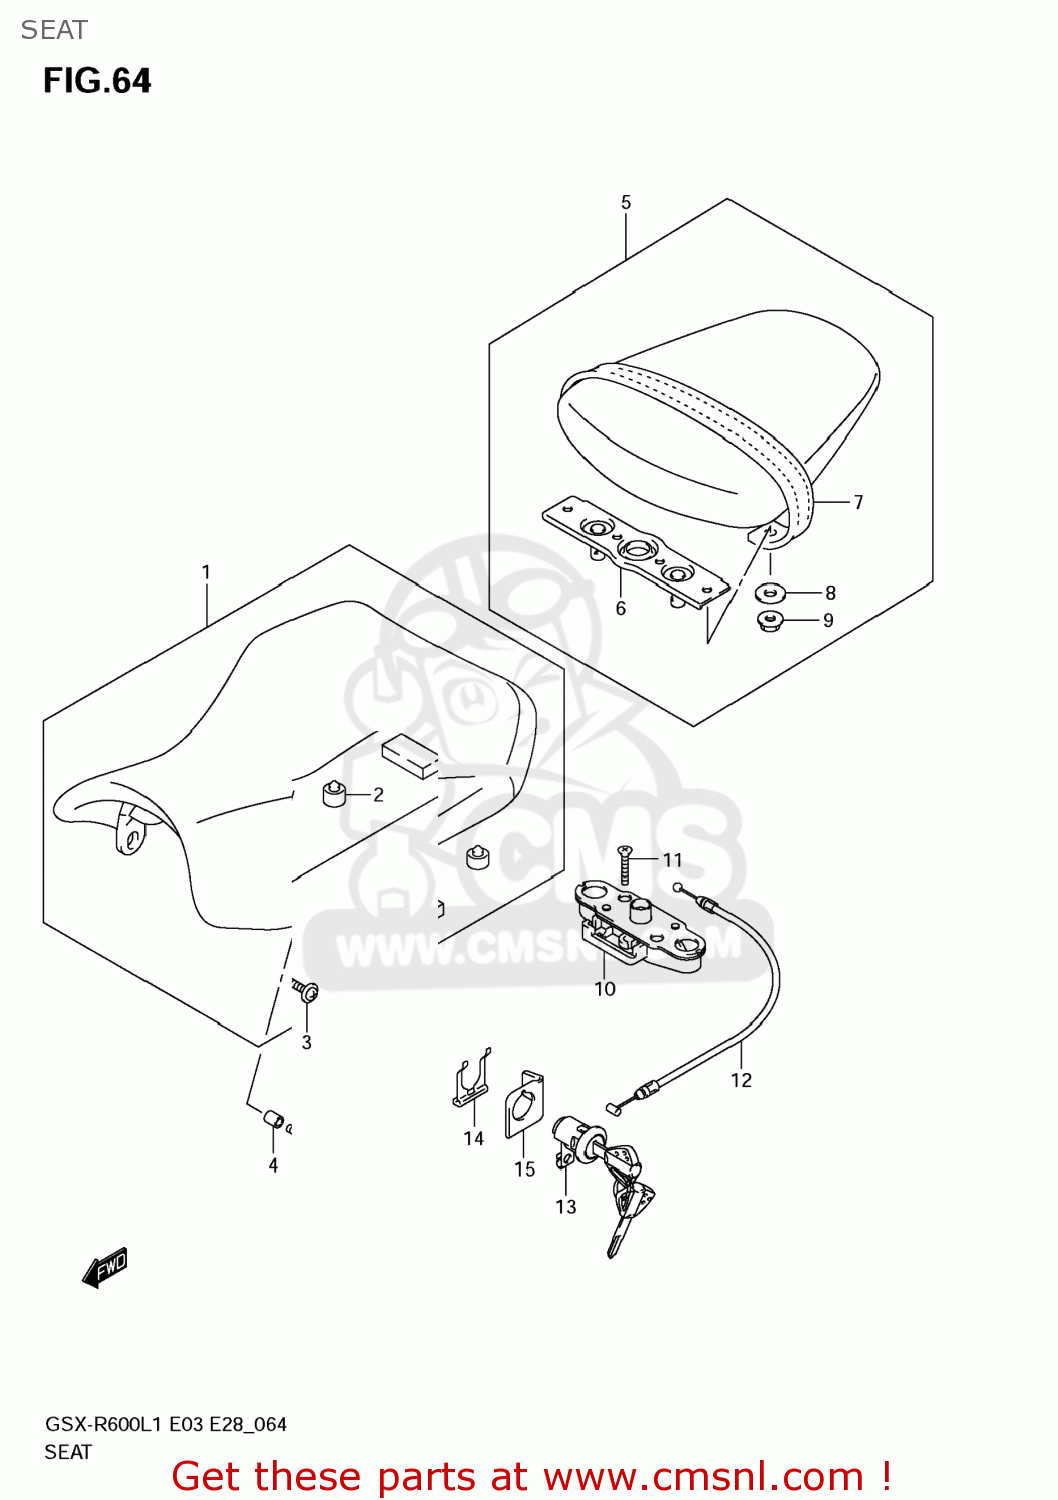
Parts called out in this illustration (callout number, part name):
1	SEAT ASSY
2	CUSHION
3	SCREW(6X25)
4	SPACER(6.5X9X10.5)
5	SEAT ASSY.PILLI
6	STRIKER
7	BAND ASSY,SEAT
8	WASHER(6.5X20X1.6)
9	NUT
10	BRACKET,SEAT SUPPORT
11	SCREW
12	CABLE,SEAT LOCK
13	LOCK SET,SEAT
14	PLATE,SEAT LOCK ASSY
15	GUIDE,SEAT LOCK CABLE
